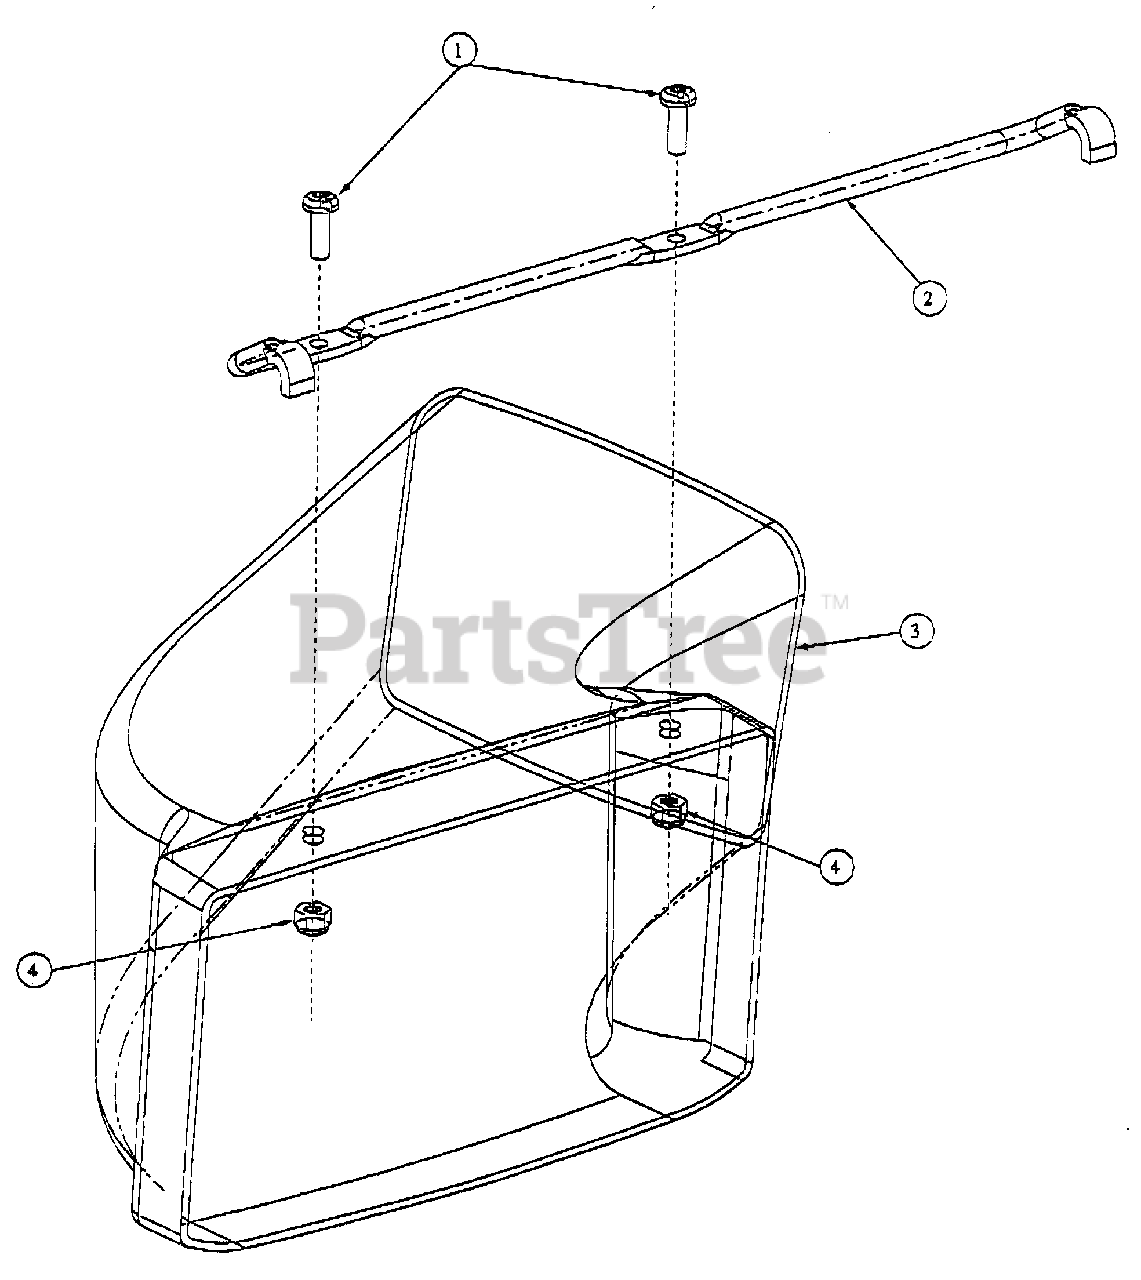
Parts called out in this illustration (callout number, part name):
1	Machine Screw, 1/4-20, .750, PANTRXI
2	21" Side Chute Mounting Rod
3	21" Side Chute Spiral Deck
4	Hex Nut 1/4-20, GRC, Lock
